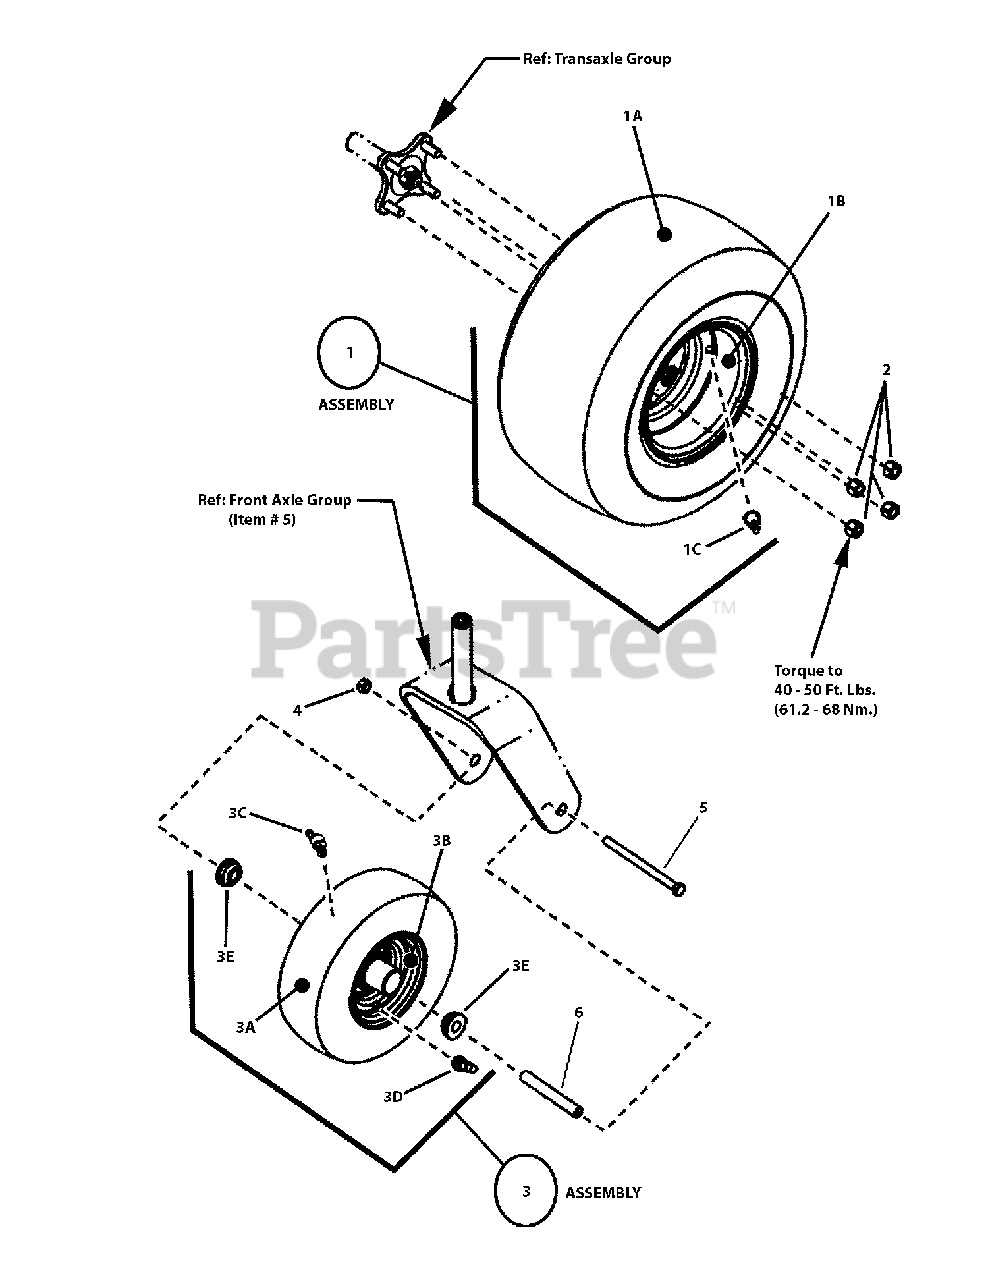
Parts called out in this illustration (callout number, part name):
1	ASSEMBLY, Tire & Wheel (Rim) (incl. 3 items shown below)
1A	TIRE, 20 x 10.00-8 K500 Tread Kenda
1A	TIRE, 18 x 9.50, K500 Tread Kenda
1B	RIM, 8 x 7.00, 4 Hole
1C	AIR VALVE STEM, Snap-In
2	LUG NUT, 1/2 - 20 Tapered Seat, YZ
3	ASSEMBLY, Wheel & Tire, ZTS 11 x 4-5 (incl. items 3A thru 3E)
3A	TIRE, 11 x 4-5
3B	RIM, w/bushings
3C	GREASE FITTING, (8M x 1 threads, 45 degree)
3D	VALVE, Air
3E	BUSHING, 5/8" I.D.
4	NUT, 7/16-14 Hex Center Lock, GR 5 or B
5	SCREW, 7/16-14NC x 6", Hex Head Cap, GR 5, YZ
6	TUBE, Caster Wheel, 0.625 OD 4.53 OLG 0.625 OD
